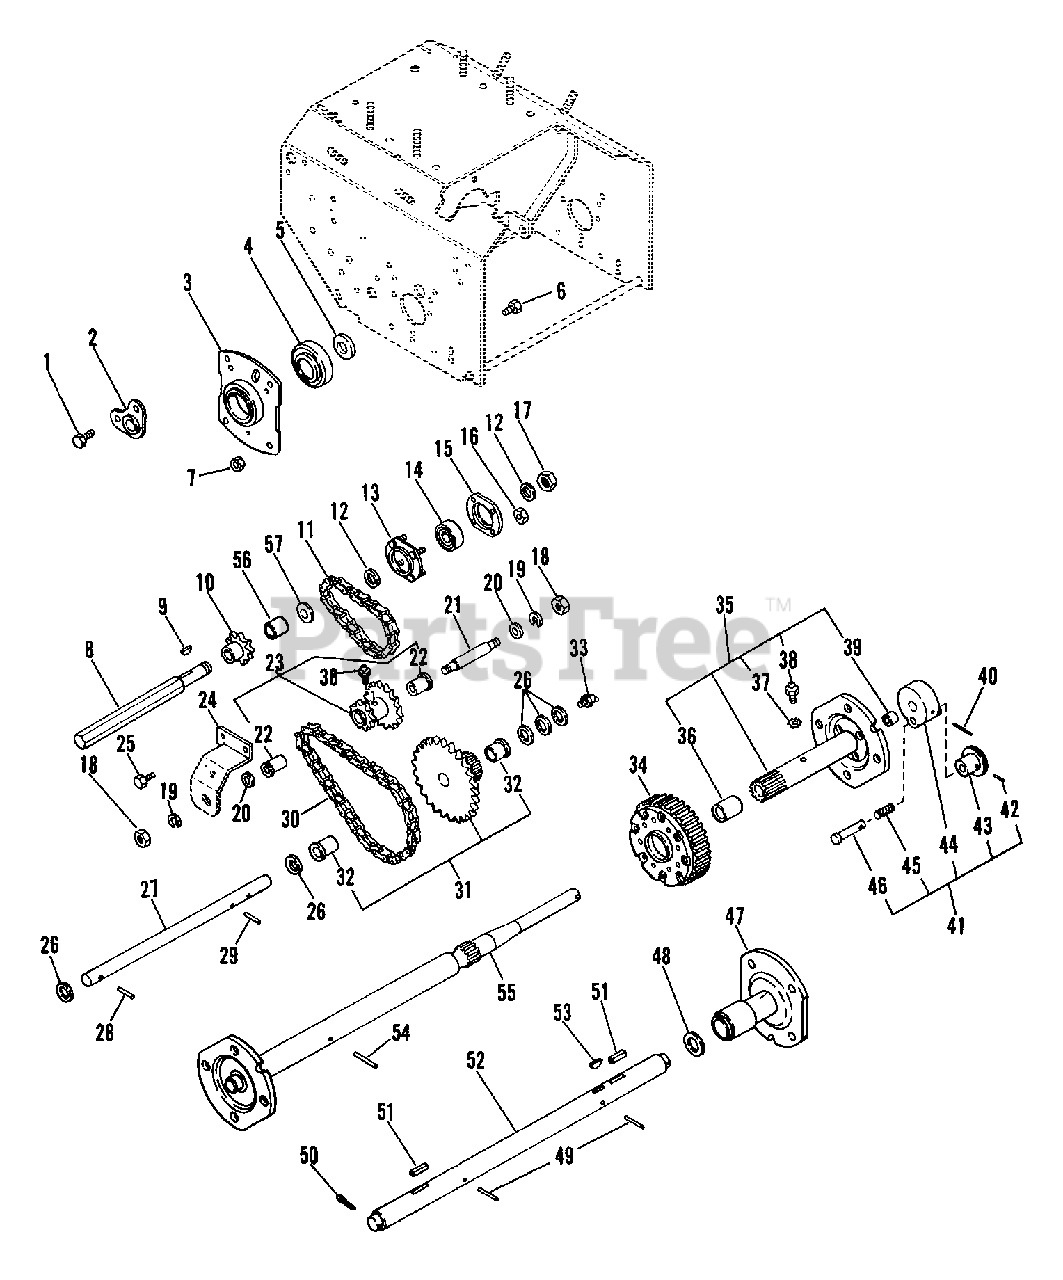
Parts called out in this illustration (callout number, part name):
1	SCR-TAP .250-20X.37 HWH PL TR
2	SUPPORT, SHAFT
3	SUPPORT, BEARING
3	BEARING RETAINER
4	BRG-BALL 1.13X2.18X.63
4	BRG-BALL 1.13X2.19X.63
4	BSHG-FLG .750X1.000X.625X1.250
5	WSHR-FL-STL .755X1.375X.125
5	WSHR-FL-STL 1.140X1.718X.134
6	SCR-SLTR-SERNK .25-20X.62 PL
6	BLT-SERNK SL .25-20X.50 PL
7	NUT-LK-FLG .250-20 PL
8	HEX SHAFT
9	KEY-WDRF .125X.625X.250 SAE5
10	9 TOOTH SPROCKET
11	CHAIN
11	IDLER CHAIN
12	WSHR-FL-STL .531X1.062X.095 PL
13	BEARING FLANGE
14	BRG-BALL .500X1.38X.437
15	BEARING FLANGE
16	NUT-LK DUAL FACE 10-24 PL
17	NUT-LK-CTR .50-20 PL
18	NUT-HEX .375-16
19	WSHR-LK .375X.130
20	WSHR-FL-STL .382X.812X.062
21	REDUCTION SHAFT
22	BSHG-SLV .500X.625X.500 BR
23	SPROCKET ASSEMBLY
24	SUPPORT, SHAFT
24	CLUTCH STOP
25	SCR-TAP .250-20X.50 HXSLHDPL
26	WSHR-FL-STL .630X1.005X.062 PL
27	PINION SHAFT
28	PIN-ROLL .156X1.00
29	PIN-ROLL .125X1.00
30	PINION CHAIN
31	PINION AND SPROCKET ASSY.
31	PINION & SPROCKET ASSEMBLY
32	BSHG-FLG .625X.750X.500X.875BR
33	HYDRAULIC DRIVE FITTING
34	SPUR GEAR, FELLOWS 35T .750 ID
34	DIFFERENTIAL ASSEMBLY
35	L.H. AXLE ASSEMBLY
35	L.H.AXLE ASSEMBLY
36	BSHG-SLV .750X.814X .750 BRZ
37	WSHR-LK .250X.047 LT PL
38	SPIN DRIVE ZERK FITTING
39	BSHG-SLV .562X.625X.625 BRZ
40	PIN-GRV .250X1.75 TP C
41	LOCKOUT HUB ASSEMBLY
42	PIN-ROLL .093X1.00
43	KNOB
44	LOCKOUT HUB
45	SG-COMP .028X.34X1.062 WLD75
46	PIN
47	WHEEL HUB
48	WSHR-FL-STL .755X1.375X.125
48	WSHR-FL-STL .880X1.380X.062
49	PIN-ROLL .188X1.25
50	PIN-COTR .12 X 1.25 PL
51	KEY-FTHR .188X1.25X.187 SAE
52	AXLE SHAFT
53	KEY-WDRF .25X.875X.375 SAE A
53	KEY-WDRF .25X.750X.313 SAE91
54	PIN-ROLL .188X1.50
55	R H AXLE
56	ROLLER
57	WSHR-FL-STL .505X1.000X.062
